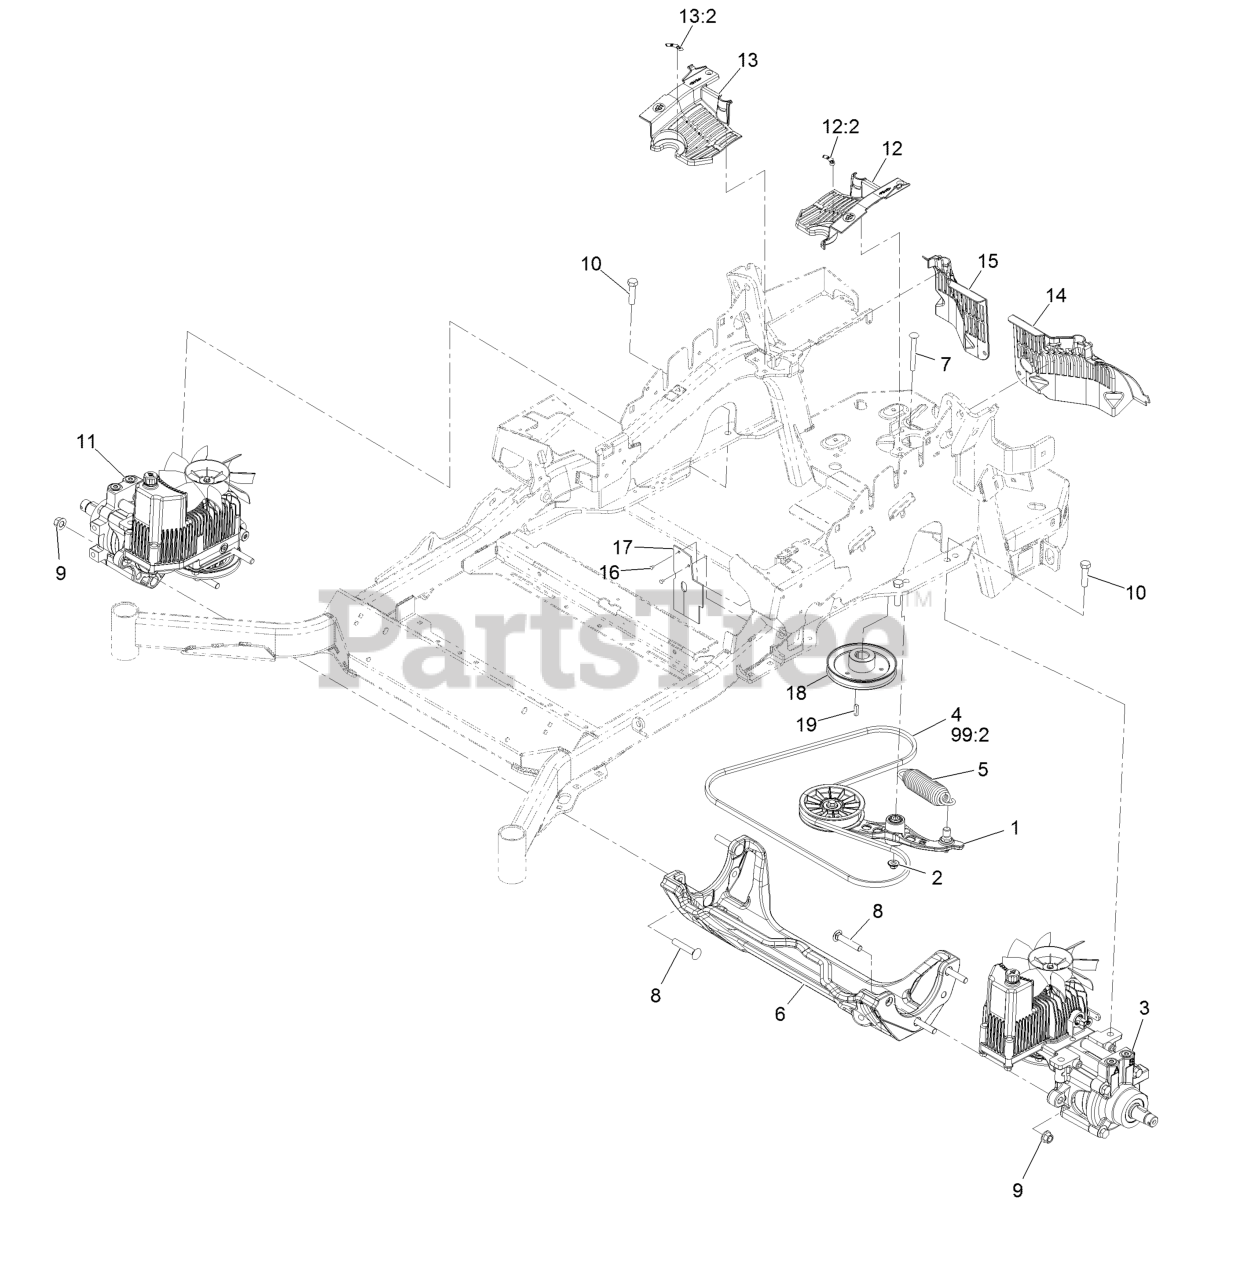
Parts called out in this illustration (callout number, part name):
1	Pump Idler ASM
2	Nut-Nyloc 3/8-16 Flg
3	LH Hydro ASM (16Cc W/Shock)
4	Belt
5	Spring-Extension
6	Cradle-Hydro
7	Bolt-Carriage Shoulder 3/8-16 X 3 1/2
8	Screw-CARR
9	Nut-Lock 1/2-13
10	Screw-HH 1/2-13 X 1 1/4
11	RH Hydro ASM (16Cc W/Shock)
12	LH Hydro Guard ASM
12:2	Decal-Oil, Hydro
13	RH Hydro Guard ASM
13:2	Decal-Oil, Hydro
14	Guard-Hydro, Rear (LH)
15	Guard-Hydro, Rear (RH)
16	Rivet 3/16 X 1/4
17	Deflector-Air Flow
18	Sheave
19	Key-Machine 1/4 X 1/4 X 1
99	Bottle-Oil, 32Oz Hydraulic
99	Filter-Hydro
99	Bottle,Oil 1 Gallon Hydraulic
99	Kit, Hydro Service
99:1	Bottle-Oil, 32Oz Hydraulic
99:2	Belt
99:3	Filter-Hydro
